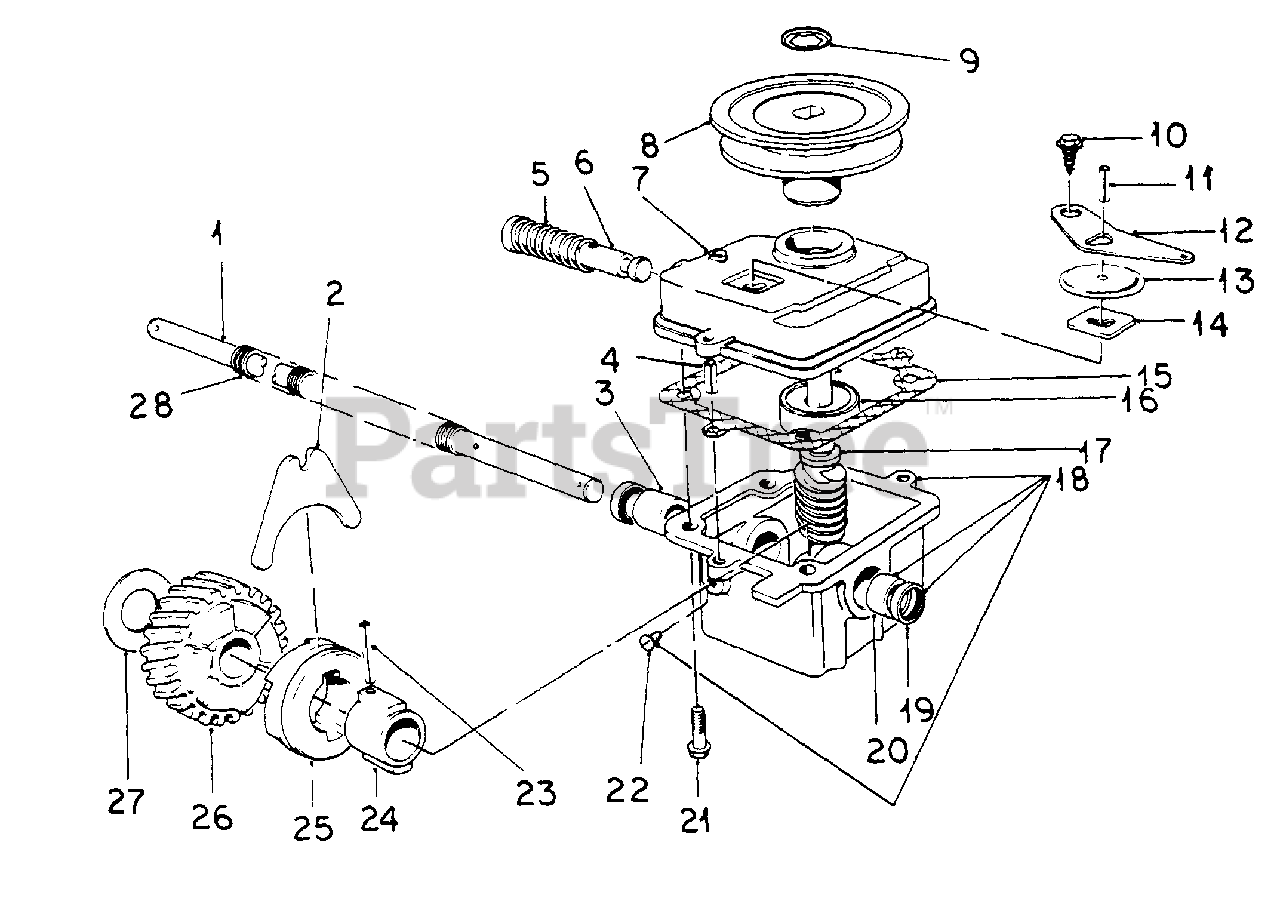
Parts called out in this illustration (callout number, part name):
1	ROD, DRIVE
2	FORK, SHIFTER
4	PIN, 3/16 X 1/2 HVY PLN CLD SPRING
6	PIN, SHIFTER
7	COVER, GEAR CASE
8	PULLEY, DRIVEN
9	RING, RETAINING
10	SCREW, NO. 10 X 1/2 H/WHD TAP
11	PIN, 5/32 X 3/4 HVY PLN CLD SPR
12	ARM, SHIFTER
14	PLATE, LATCH
15	GASKET, GEAR CASE
16	BEARING, BALL
17	SHAFT, WORM
18	CASE, ASSY GEAR
22	SCREW, 1/4-20 X 3/8 SHW NYLON
23	PIN, 1/8 X 3/4 HVY CLD-SPR
25	CLUTCH, JAW
26	GEAR, HELICAL
27	WASHER, THRUST
28	HOSE, DRIVE SHAFT
